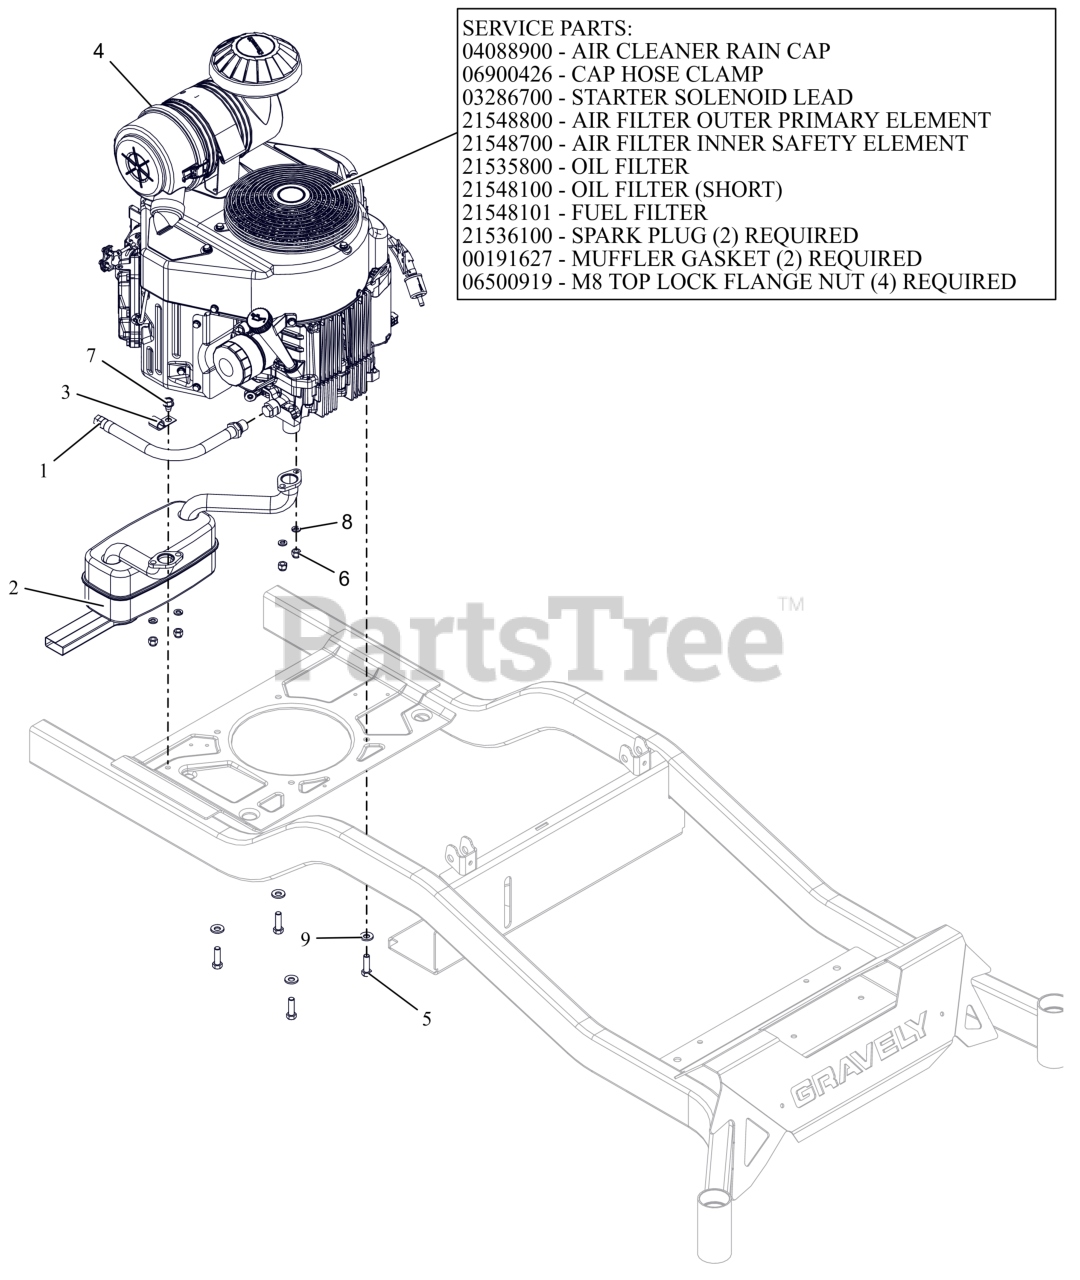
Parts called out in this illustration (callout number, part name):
1	HOSE, OIL DRAIN
2	MUFFLER, KAWASAKI
4	ENGINE, KAWASAKI FX691
4	FILTER, OUTER
4	FILTER, INNER - KAW
4	OIL FILTER, KAWASAKI FR
4	FUEL FILTER-KAWASAKI FR
4	PLUG, SPARK
4	CAP, KAW 11065-7025
4	CLAMP, HOSE #36 SS 1.813-2.75
4	LEAD - STARTER SOLENOID
4	GASKET, MUFFLER S/O
4	NUT-LK-TOP-FLG M8 ZCC
5	BLT, HEX .38-16X1.25 G5 ZCC NT
6	NUT,NYL M8-1.25 G8.8 ZCC
7	SCR,TAP .375-16X.50 HWH TR ZCC
8	WSHR,LK-REG .312X.078 ZCC
9	WASHER, 3/8" SPRING DISC
